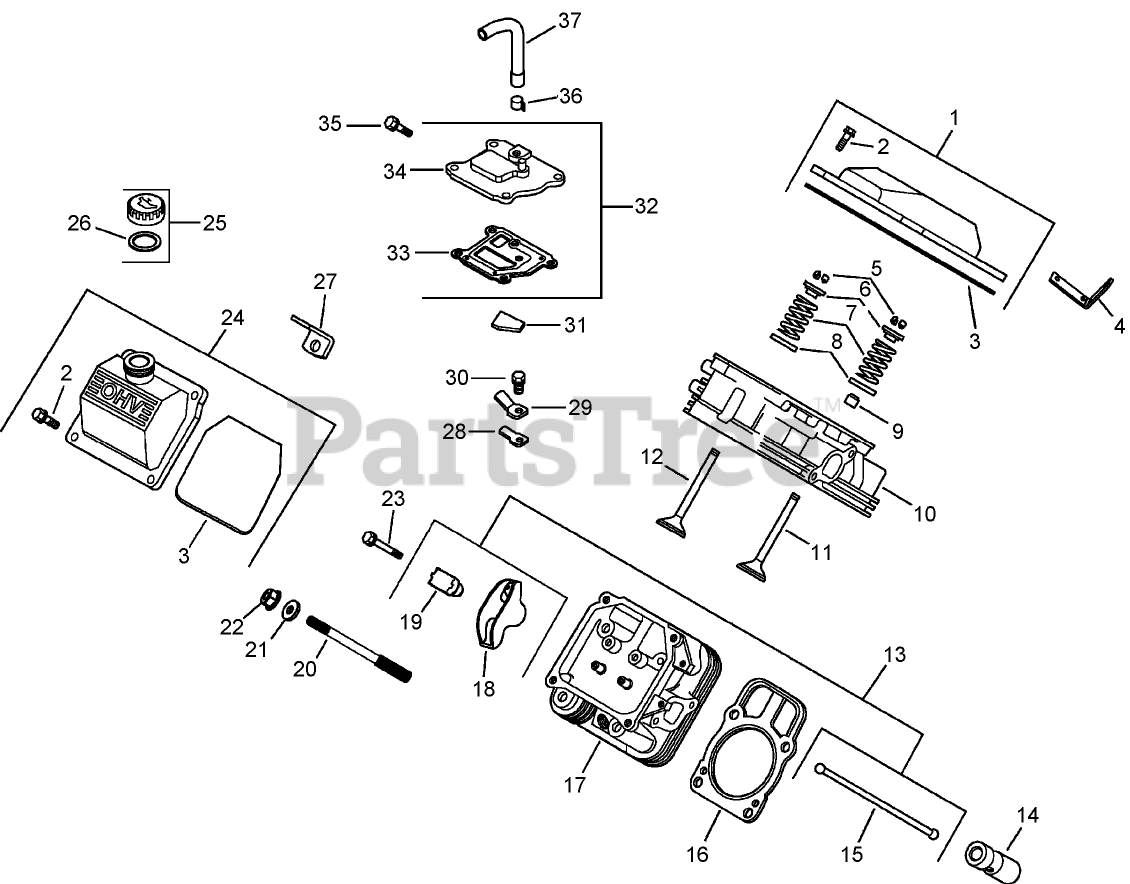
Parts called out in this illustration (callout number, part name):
1	Plain Valve Cover Kit (Includes 2, 3)
2	SCREW-FLANGE (M6X1.0X30)
3	O-Ring
4	Strap-Lifting
5	RETAINER KIT
6	CAP-SPRING, VALVE
7	SPRING-VALVE
8	RETAINER-SPRING
9	SEAL-STEM, VALVE
10	No. 1 Cylinder Head ASM
11	VALVE-INTAKE (STD)
11	VALVE-INTAKE (.25)
12	VALVE-EXHAUST (STD)
12	VALVE-EXHAUST (.25)
13	Valve Train Kit (Includes 15, 18, 19)
14	Lifter-Valve
15	ROD-PUSH
16	Cylinder Head Gasket Kit (Includes head mounting hardware)
17	No. 2 Cylinder Head ASM
18	ARM-ROCKER
19	Pivot-Arm, Rocker
20	STUD (M8X1.25xM10X1.5x105MM)
21	WASHER-FLAT (8.6 MM)
22	NUT-FLANGE (M8X1.25)
23	Screw
24	Oil Fill Valve Cover Kit (Includes 2, 3)
25	Oil Fill Cap ASM (Includes 27)
26	O-RING
27	Strap-Lifting
28	REED-BREATHER
29	RETAINER-REED
30	SCREW-HHFTF (M5X.80X10)
31	Filter-Breather
32	Breather Kit (Includes 21, 34)
33	GASKET-BREATHER
34	COVER-BREATHER
35	SCREW-HHFTF (M6X1.0X20)
36	Clamp-Hose
37	Hose-Breather
